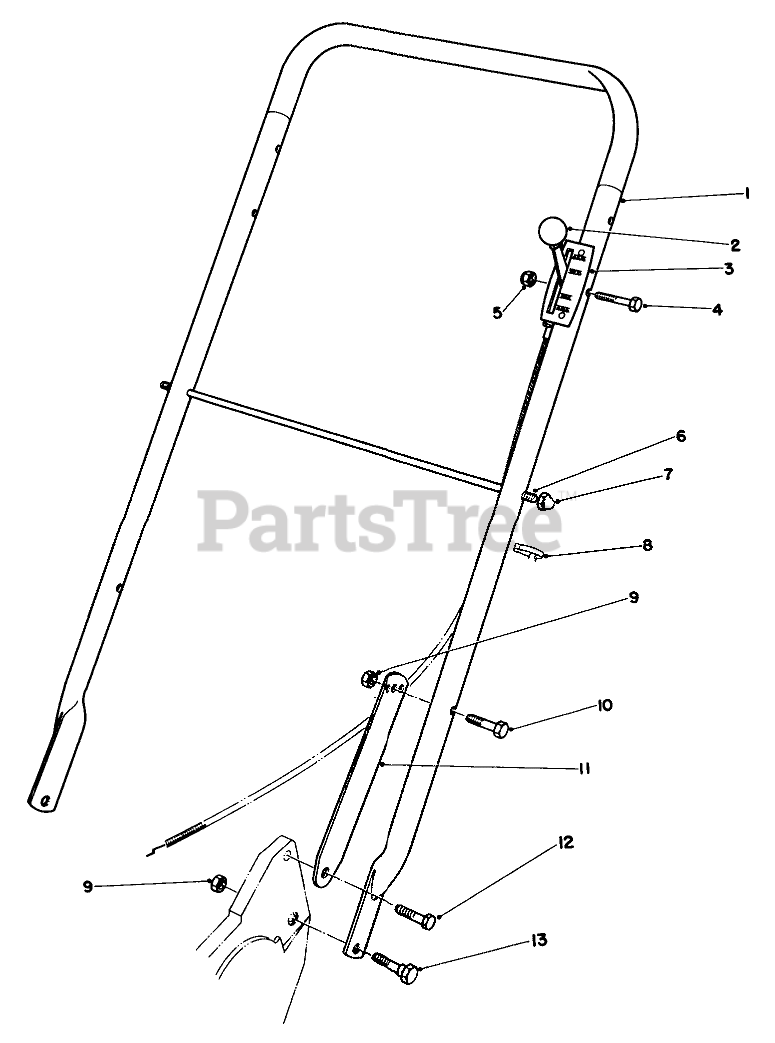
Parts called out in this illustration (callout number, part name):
1	Handle
2	KNOB-CONTROL
3	Control-Throttle (Incl. Ref. #2)
4	SCREW-HH
5	NUT-LOCK, NI
6	ROD-SUPPORT, BAG
7	NUT-CAP
9	NUT-LOCK, CONE
10	SCREW-HH
11	Latch-Handle
12	SCREW-HH
13	SCREW-SHOULDER
